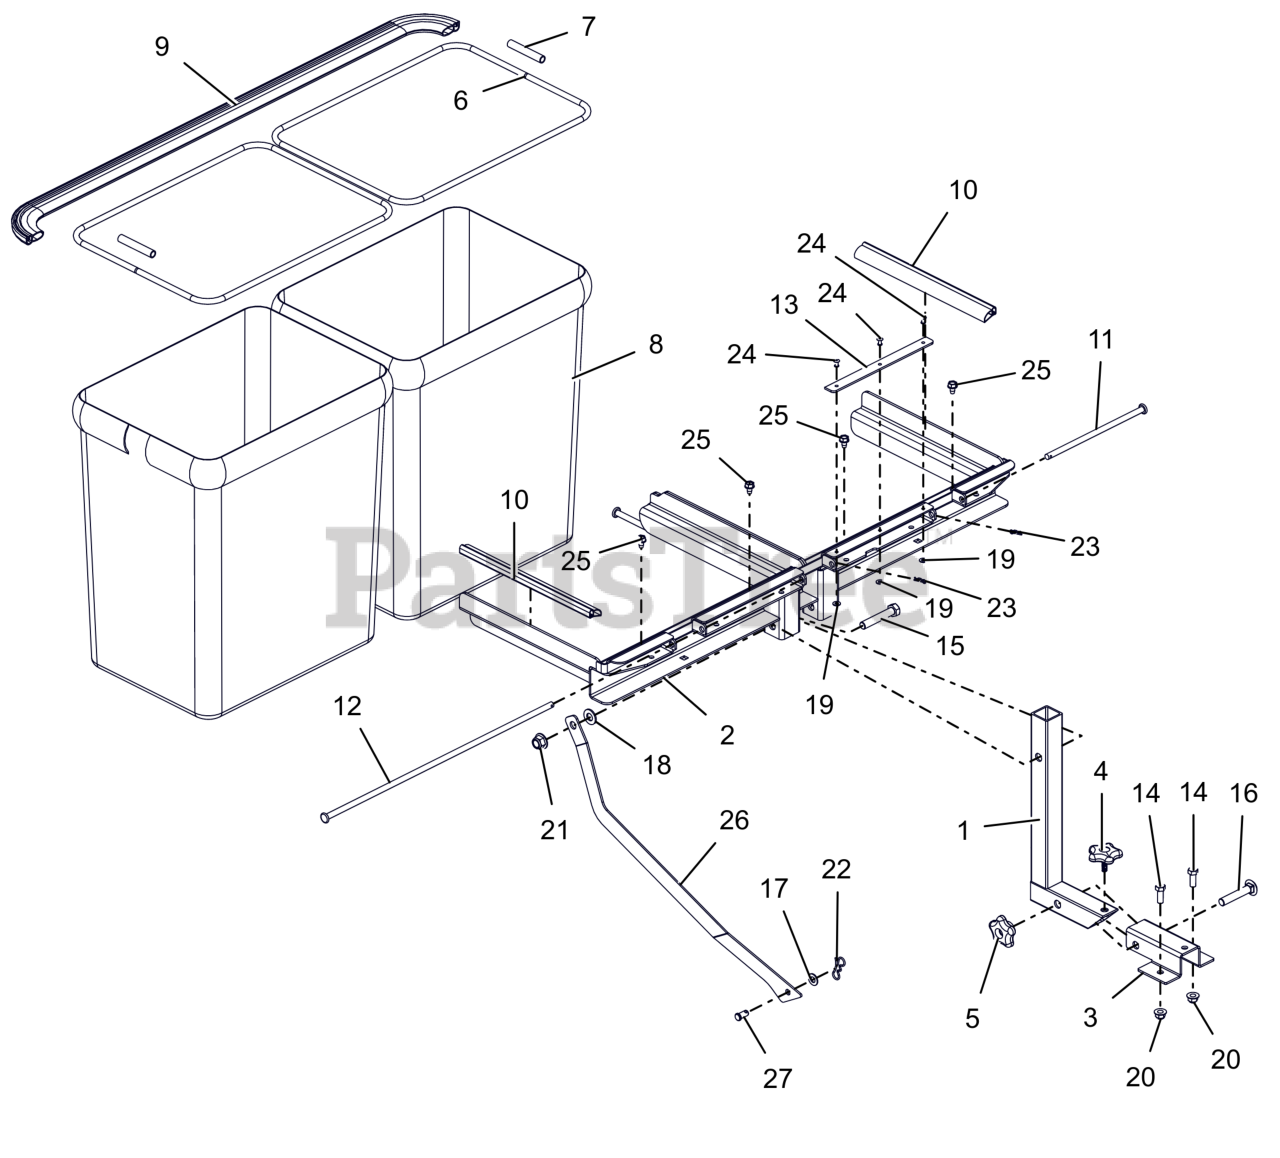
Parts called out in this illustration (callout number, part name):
1	BRKT, RECEIVER SLEEVE INSERT
2	ASS'Y, BAGGER FRAME UPPER
3	BRKT, RECEIVER LOWER
4	KNOB, WING STUDDED
5	KNOB, WING
6	FRAME, ZOOM BAG
7	HOSE, .38 X.50 X 3.00 VINYL
8	BAG, MESH ZOOM
9	SEAL, BULB - BAGGER HOOD
10	SEAL, BULK
11	PIN, BAGGER HINGE (L)
12	PIN, BAGGER HINGE (R)
13	SEAL, HINGE
14	BLT,HEX .38-16X1.00 G5 ZCC
15	BLT, HEX .50-13X2.75 G8 ZCC
16	BLT, RHSN .50-13X2.75 G5 ZCC
17	WSHR,FLT .406X.812X.065 ZCC
18	WSHR,FLT .531X1.062X.095 ZCC
19	WSHR, FLT .219X.500X.049 ZCC
20	NUT,NYL-FLG .38-16 GF ZCC
21	NUT,NYL-FLG .50-13 GF ZCC
22	PIN, BOWTIE .091X1.875 ZCC
23	PIN, HAIR #225 .072X1.09
24	RVT-POP.187X.527 DOME ST
25	SCR,TAP .312-18X.50 HWH TR ZCC
26	BRKT, BAG FRAME SUPPORT BAR (BLACK)
27	PIN-CLEV .38X.75 YWZC
